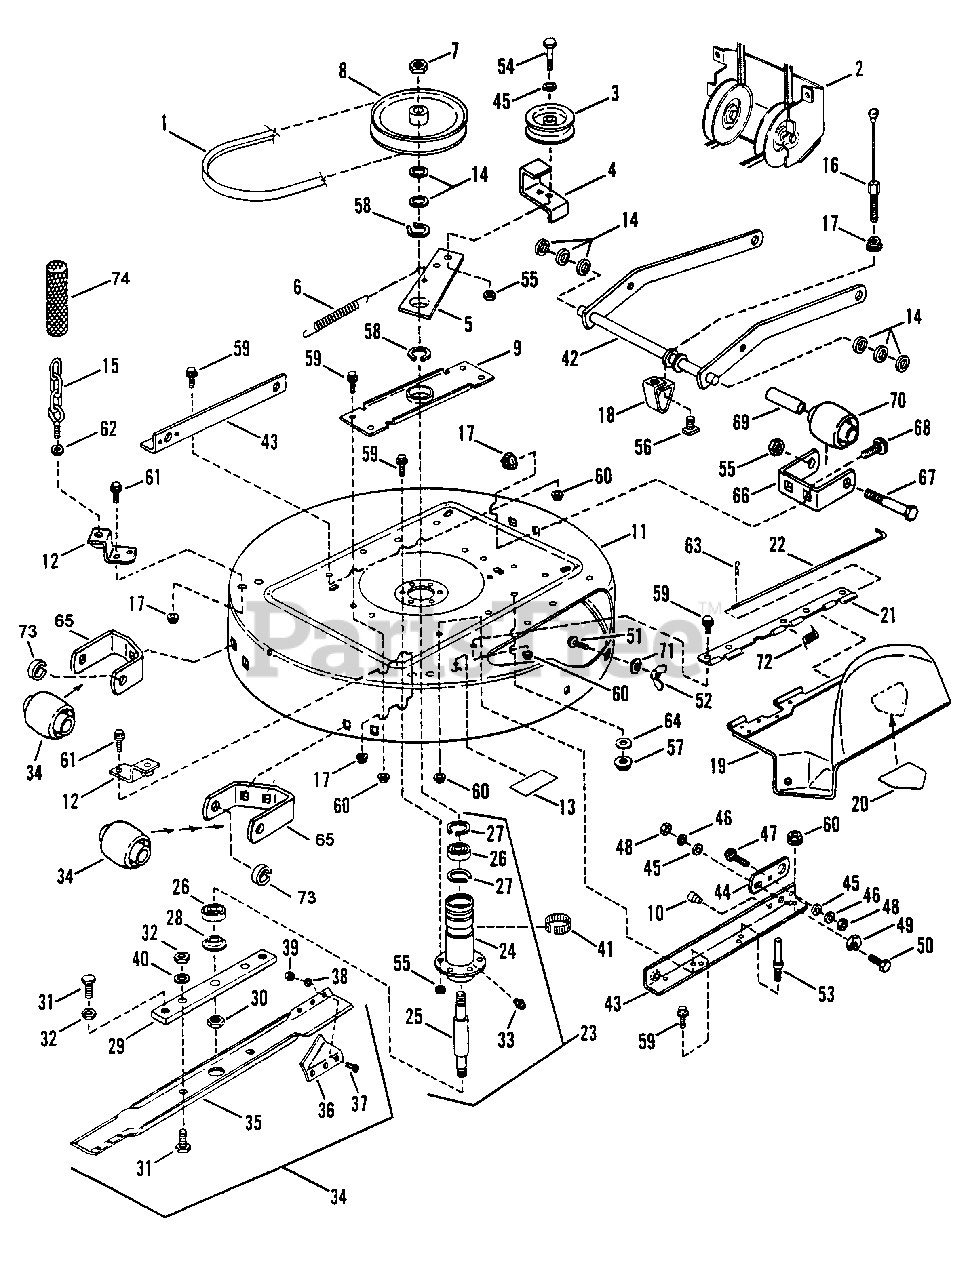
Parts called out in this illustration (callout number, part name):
1	BELT, 33" Drive
2	ASSEMBLY, Mule Drive
3	PULLEY, Idler, Flat, 4.12 O.D
4	GUIDE, Belt
5	ARM, Idler
6	SPRING, Belt Tension
7	NUT, 3/4-16 Hex Jam
8	PULLEY, 8" O.D.
9	BRACE, Spindle
10	BUMPER BUTTON
11	DECK, 33" Cutter
12	ASSEMBLY, Brkt. Rear Lift
13	DECAL-CAUTION, Deflector in Place
14	WASHER, Shim
15	ASSEMBLY, Adj. Bolt-Chain
16	CABLE, Front Lift
17	NUT, 5/16-18 Hex Flange Lock
18	BRACKET, Front Lift Hanger
19	ASSEMBLY, Deflector
20	DECAL-DANGER (Cut Finger)
21	HINGE, Side Chute
22	PIN, Hinge
23	ASSEMBLY, Spindle
24	HOUSING, Spindle
25	SPINDLE, 33" Mower Deck
26	BEARING, Spindle
27	RING, Retaining
28	WASHER, Spindle
29	HOLDER, Blade
30	NUT, 5/8-18 Hex Lock
31	SCREW, 1/2-20 x 1" Hex Head Cap (Grade 5)
32	JAM-NUT, 1/2-20 Hex
33	FITTING, Lube (Press fit for .187 hole-no ball)
34	WHEEL, Gage
35	BLADE, 33" Mower Deck
36	AIR-LIFT
37	SCREW, 5/16-24 x 11/16" Machine, Grade 5
38	WASHER, 5/16-24 Internal Tooth Lock
39	NUT, 5/16-24 Hex
40	WASHER, 1/2 Internal Tooth Lock
41	RING, Tolerance
42	WELDMENT, Front Lift Arm
43	RAIL, Lift Arm
44	LINK-ADJUSTMENT
45	WASHER, 3/8 SAE
46	WASHER, 3/8 Split Lock
47	BOLT, 3/8-16 x 3/4" Carriage, Gr.
48	NUT, 3/8-16 Hex
49	RING, Adjustment
50	SCREW, 3/8-16 x 1" H.H. Cap, Gr. 5
51	BOLT, 5/16-18 x 3/4" Sh. Nk. Carr, Gr. 5
52	WING-NUT, 5/16-18
53	STUD, Deck Stop
54	SCREW, 3/8-24 x 1-1/2" H.H.C., Gr. 2
55	NUT, 3/8-24 Hex Lock
56	T-NUT, 5/16-18
57	NUT, 3/8-24 Hex, Grade 2
58	RING, 2" External Retaining
59	BOLT, 3/8-16 x 3/4" Hex Flng. Lock
60	NUT, 3/8-16 Hex Flange Lock
61	BOLT, 5/16-18 x 1/2" Hex Flange Lock, (Grade 5)
62	NUT, 3/8-16 Hex Jam
63	PIN, Hair Cotter
64	LOCKWASHER, 3/8 Internal Tooth
65	BRACKET, Gage Wheel (Rear)
66	BRACKET, Gage Wheel (Front)
67	SCREW, 3/8-24 x 3-3/4 H.H.C., Gr. 5
68	BOLT, 5/16-18 x 1/2" Short Neck Carriage Grade 5
69	SPACER
70	WHEEL, Gage
71	WASHER, 5/16 Flat
72	SPRING, Hinge
73	RING
74	COVER, Chain
